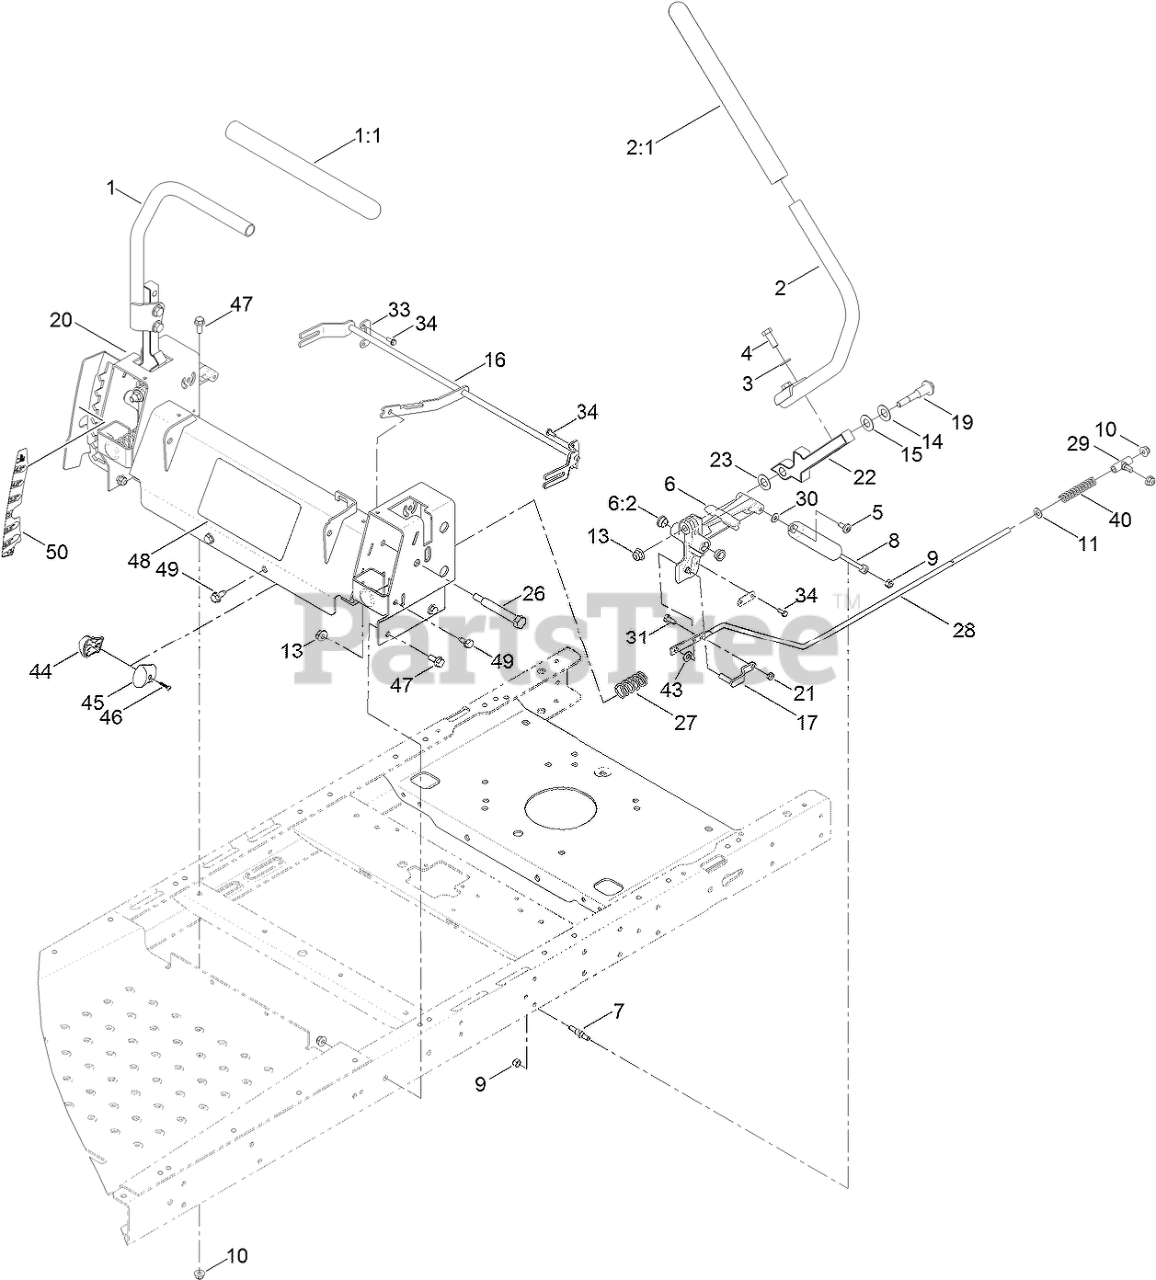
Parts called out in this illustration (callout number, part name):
1	HANDLE-CONTROL, RH
2	HANDLE-CONTROL, LH
3	WASHER-FLAT
4	SCREW-HH
5	SCREW-SHOULDER
6	ACTUATOR ARM ASM
6:2	BUSHING-FLANGE
7	STUD-DAMPER
8	Damper-Control, Motion
9	NUT-LOCK, NI
10	NUT-HF, NI
11	WASHER-PLAIN
13	NUT-HF, NI
14	WASHER-BELLEVILLE
15	WASHER
16	SPEED CONTROL ASM
17	PIN-ROD, HYDRO
19	BOLT-PIVOT
20	CONTROL BOX ASM
21	NUT-LOCK, NI
22	LEVER-CONTROL
23	WASHER-NYLON
26	BOLT-PIVOT
27	SPRING-RETURN
28	ROD-HYDRO
29	MOUNT-ROD, HYDRO
30	WASHER
31	SCREW-HH
33	RETAINER
34	SCREW-TAPTITE
40	SPRING-RETURN, NEUTRAL
43	SPACER-NYLON
44	KNOB-RH
45	KNOB-LH
46	SCREW-PPH
47	SCREW-HHF
48	DECAL-CONTROL, SPEED
49	SCREW-HWHTF
50	DECAL-HOC
